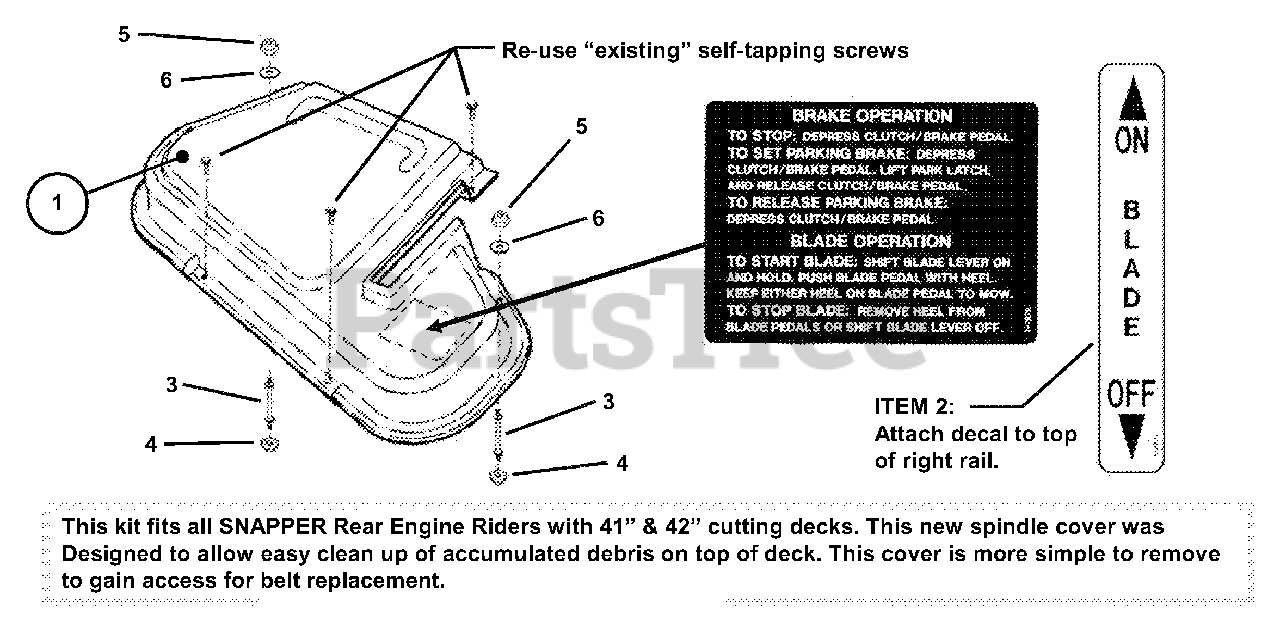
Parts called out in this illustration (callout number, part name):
1	ASSEMBLY, Belt Cover and Brake/Blade Operation Decal
2	DECAL, Blade
3	STANDOFF, 3-1/2"
4	NUT, 3/8-16 Hex Flange Lock
5	NUT, 5/16-18 Hex Nyloc
6	WASHER, .453 I.D., Flat
